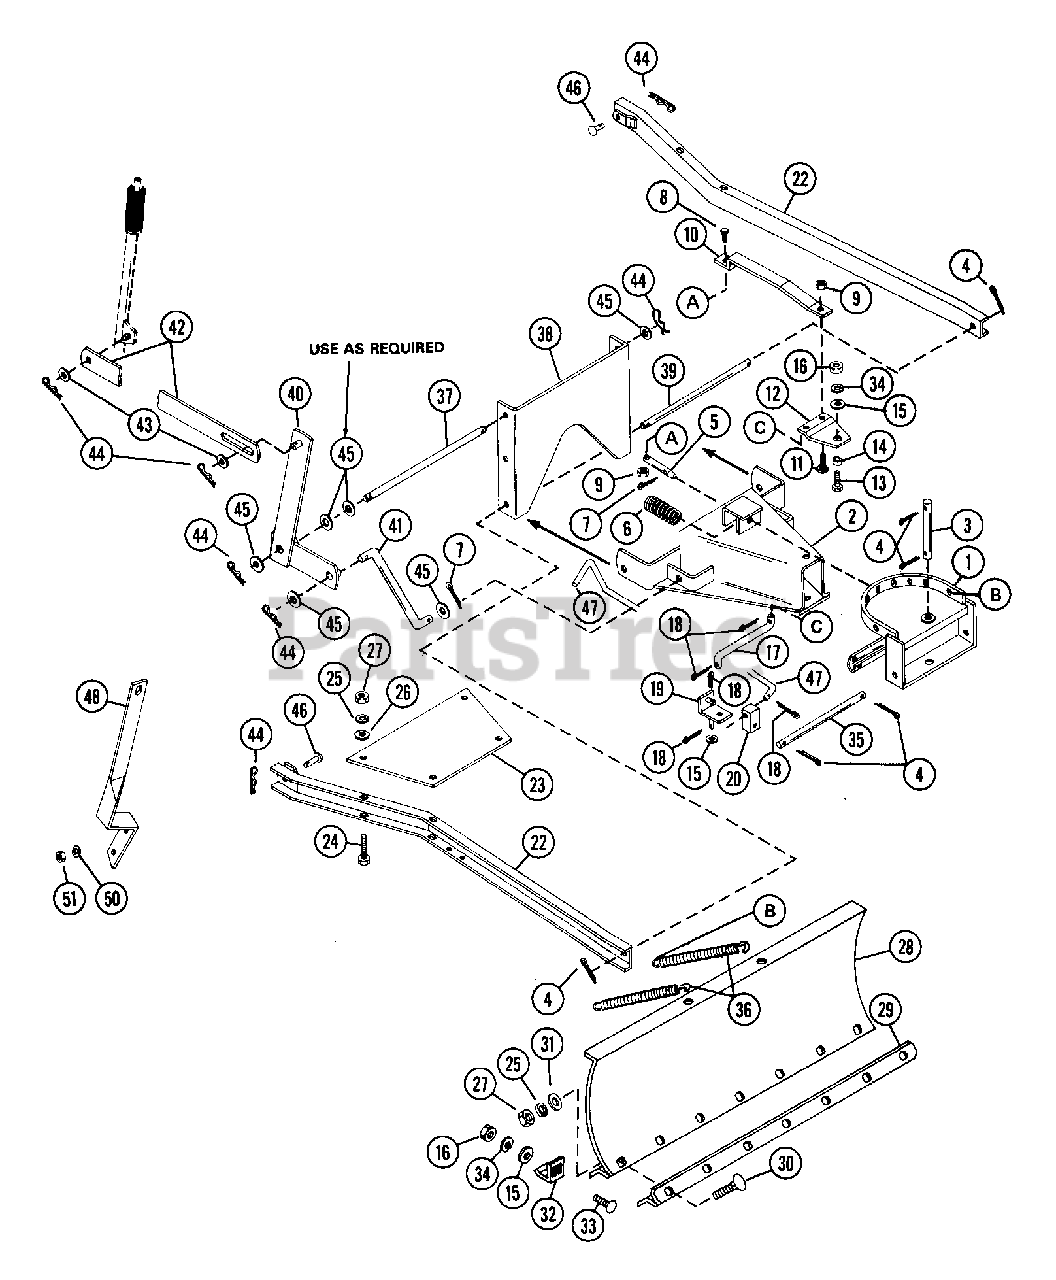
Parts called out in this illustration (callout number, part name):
1	SUPPORT
2	PUSH FRAME
4	PIN-COTR .18X1.0 PL
5	LATCH PIN
6	SG-COMP .080X.85X1.44
7	PIN-COTR .12X1.0 PL
8	BLT-HEX .31-18X1.25 PL GR2
9	NUT-LK .312-18 GR A PL
11	BLT-RDHDSQNK .312-18X.62SHTPL
12	PIVOT PLATE
13	BLT-HEX .38-16X1.00 PL
14	SPACER .406X.749X.162
15	WSHR-FL-STL .438X1.0X.083 PL
16	NUT-HEX .375-16
18	PIN-COTR .12X.75 PL
20	UNIVERSAL BLOCK JOINT
22	CHANNEL
23	STIFFNER PLATE
24	BLT-HEX .31-18X2.50 PL GR5
25	WSHR-LK .312X.097 PL HVY
26	WSHR-FL-STL .323X.625X.062 PL
27	NUT-HEX .312-18
28	WELDMENT, SNOW BLADE
29	WEAR PLATE
30	BLT-RDHDSQNK .31-18X1.00 PL
31	WSHR-FL-STL .38X.875X.083 PL
32	SKID SHOE
33	BLT-RDHDSQNK .38-16X1.0 PL
34	WSHR-LK .375X.094 MED PL
36	SG-TENS .187X1.50X9.94 WLD 40
37	MOUNT ROD
38	PIVOT SUPPORT
39	PIVOT ROD
40	LIFT BELLCRANK
41	LIFT LINK
42	LIFT STRAP
43	WSHR-FL-STL .531X1.062X.095 PL
44	PIN-HAIR INT .09X.188 PL
45	WSHR-FL-STL.656X1.312X.095 PL
46	PIN-CLEV .494X1.25 YWZC
47	CONTROL ROD
48	CONTROL SUPPORT
50	WSHR-LK .312X.097 PL HVY
51	NUT-HEX .312-18
